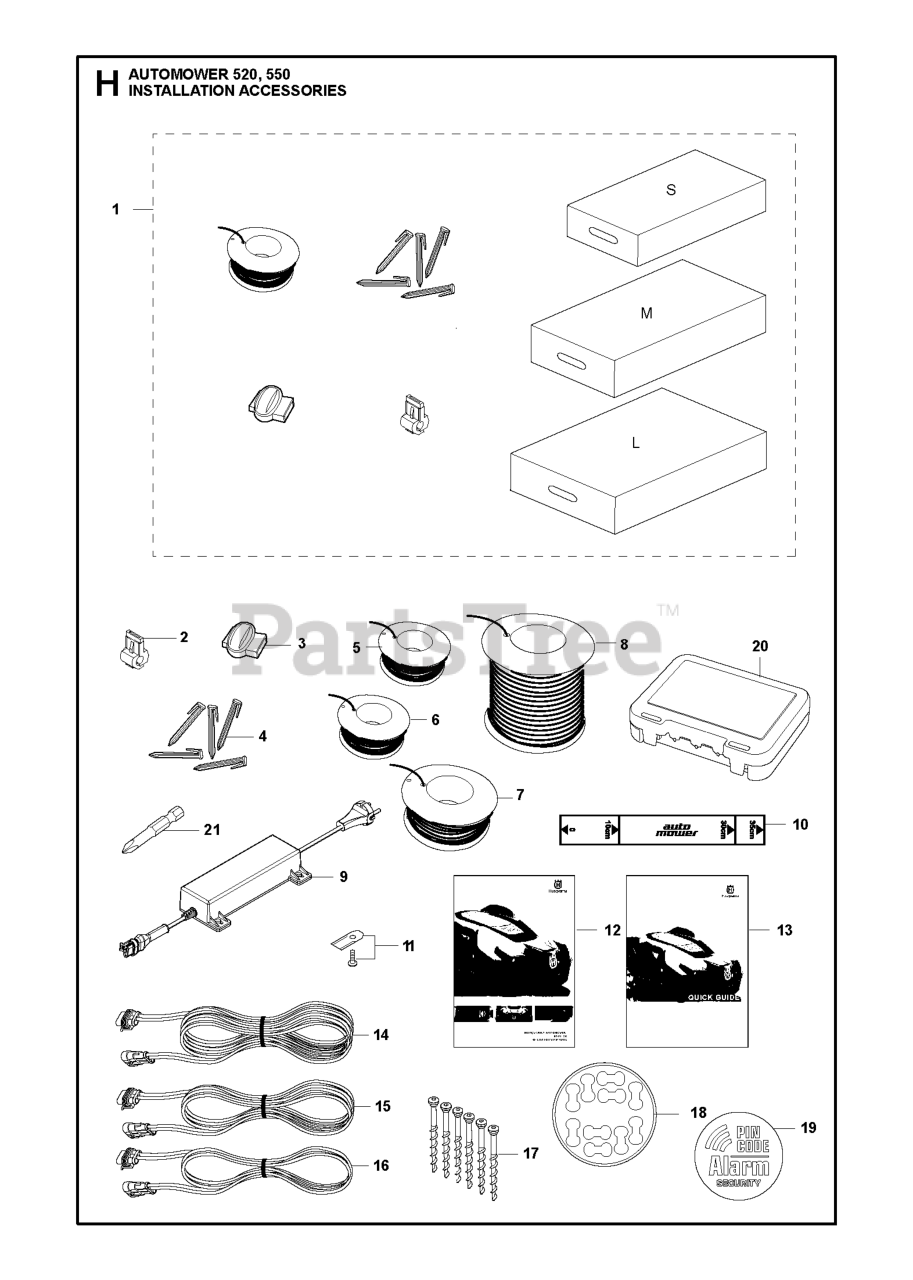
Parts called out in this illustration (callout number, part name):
1	SMALL AUTOMOWER INSTALL KIT
1	LARGE AUTOMOWER INSTALL KIT
1	MED AUTOMOWER INSTALL KIT
2	CONNECTOR 5 PCS, BLISTER
2	CONNECTOR 100 PCS
2	BRAKER
3	SPLICE KIT
3	COUPLER SPLICER, 5 PCS,
3	COUPLER SPLICER, 100 PCS
4	STAPLE 100 PCS
4	STAPLE 100 PCS, BLISTER
5	WIRE 150M, BLISTER
5	WIRE 50M STANDARD Ø2.7MM,BLIST
5	WIRE BOUNDARY 150M
6	WIRE 250M
7	WIRE 500M
8	WIRE (800M)
9	POWER SUPPLY UNIT ROBOTIC
10	RULER / CENTIMETERS
11	HUS BLADE SET 300 PCS
11	HUS BLADE SET 9 PCS
11	HUS BLADE SET 45 PCS
14	CABLE ASSY LOW VOLTAGE CABLE
15	CABLE ASSY LOW VOLTAGE CABLE
16	CABLE ASSY LOW VOLTAGE CABLE
17	SCREW KIT CS
17	SCREW 3 PCS, BLISTER PACK
18	STICKER CABLE MARKERS KIT 10PC
19	LABEL SECURITY
20	CONNECTOR PROTECTION BOX
21	WRENCH BITS CHANGING ROBOTIC B
